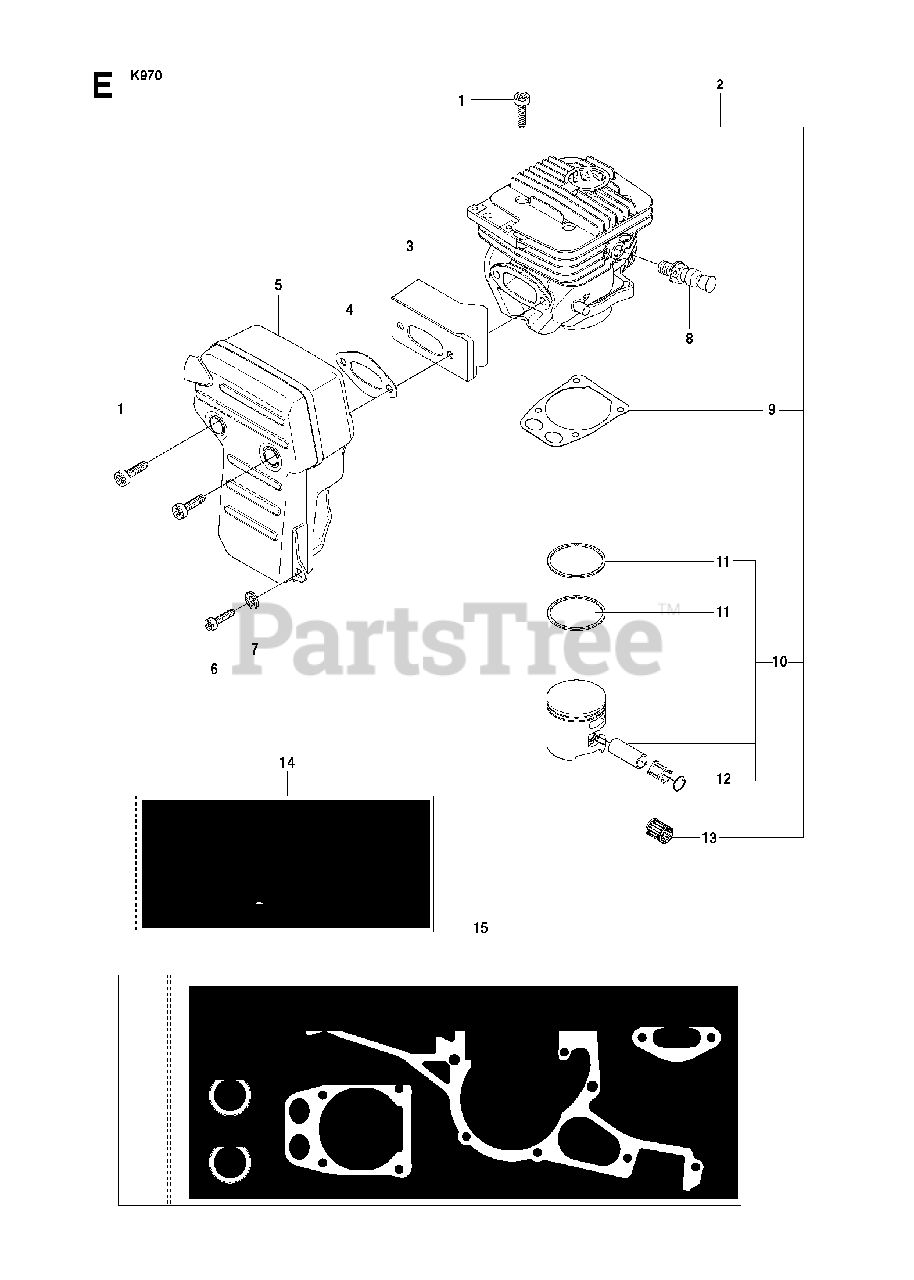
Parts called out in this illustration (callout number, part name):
1	SCREW ITXSCM
2	CYLINDER ASSY
3	HEAT DEFLECTOR
4	GASKET
5	MUFFLER ASSY
6	SCREW ITXSCM
8	DECOMPRESSION VALVE
13	NEEDLE BEARING
15	GASKET KIT
16	SEALING RING
